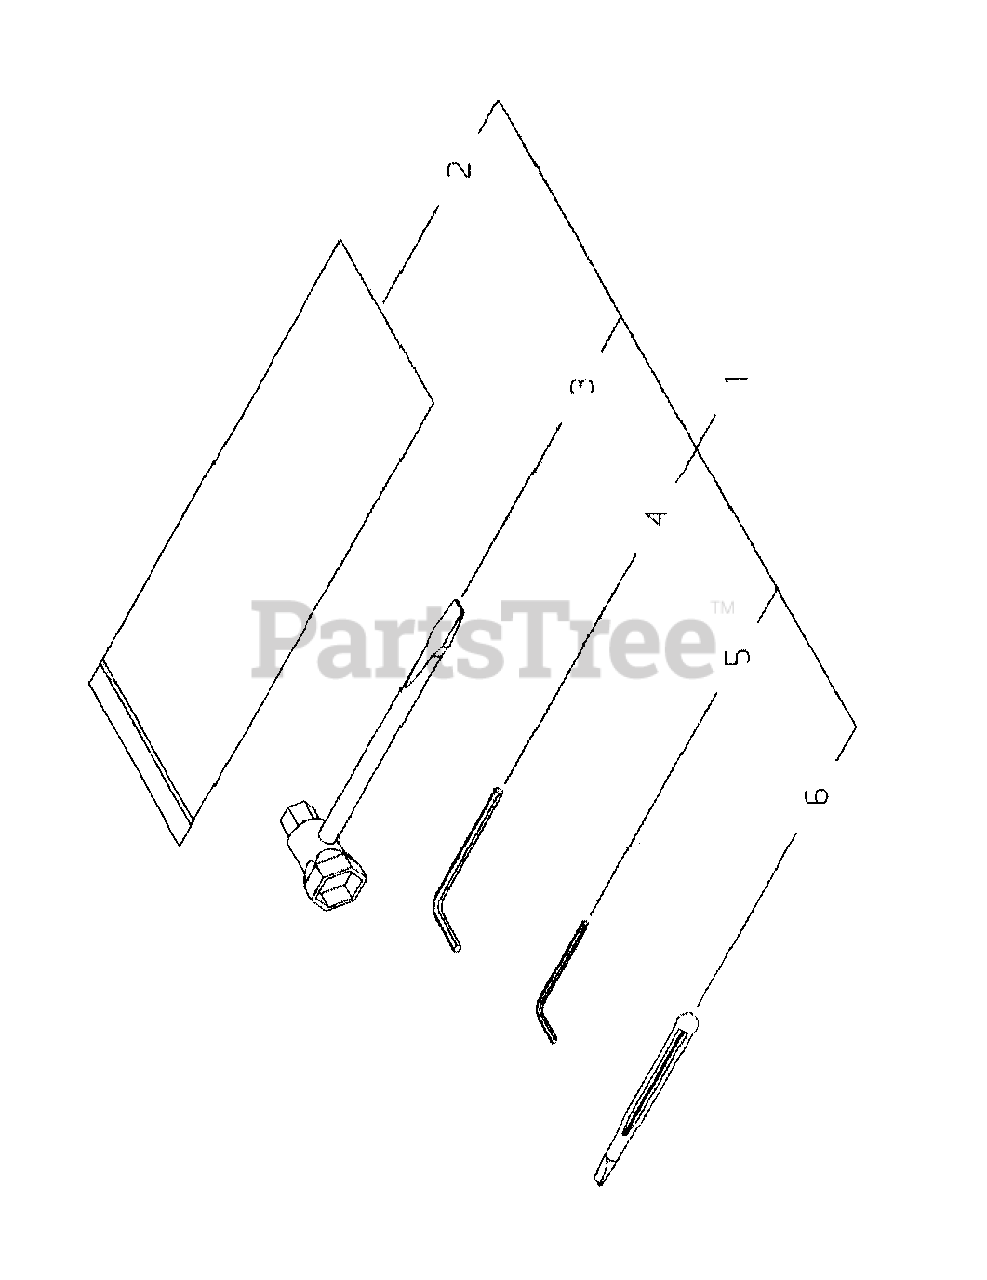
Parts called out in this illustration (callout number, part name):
1	TOOL KIT
2	BAG, TOOL
3	T-WRENCH - 13X19mm
4	HEX KEY - 4mm
5	HEX KEY - 3mm
6	SCREWDRIVER - PLASTIC
